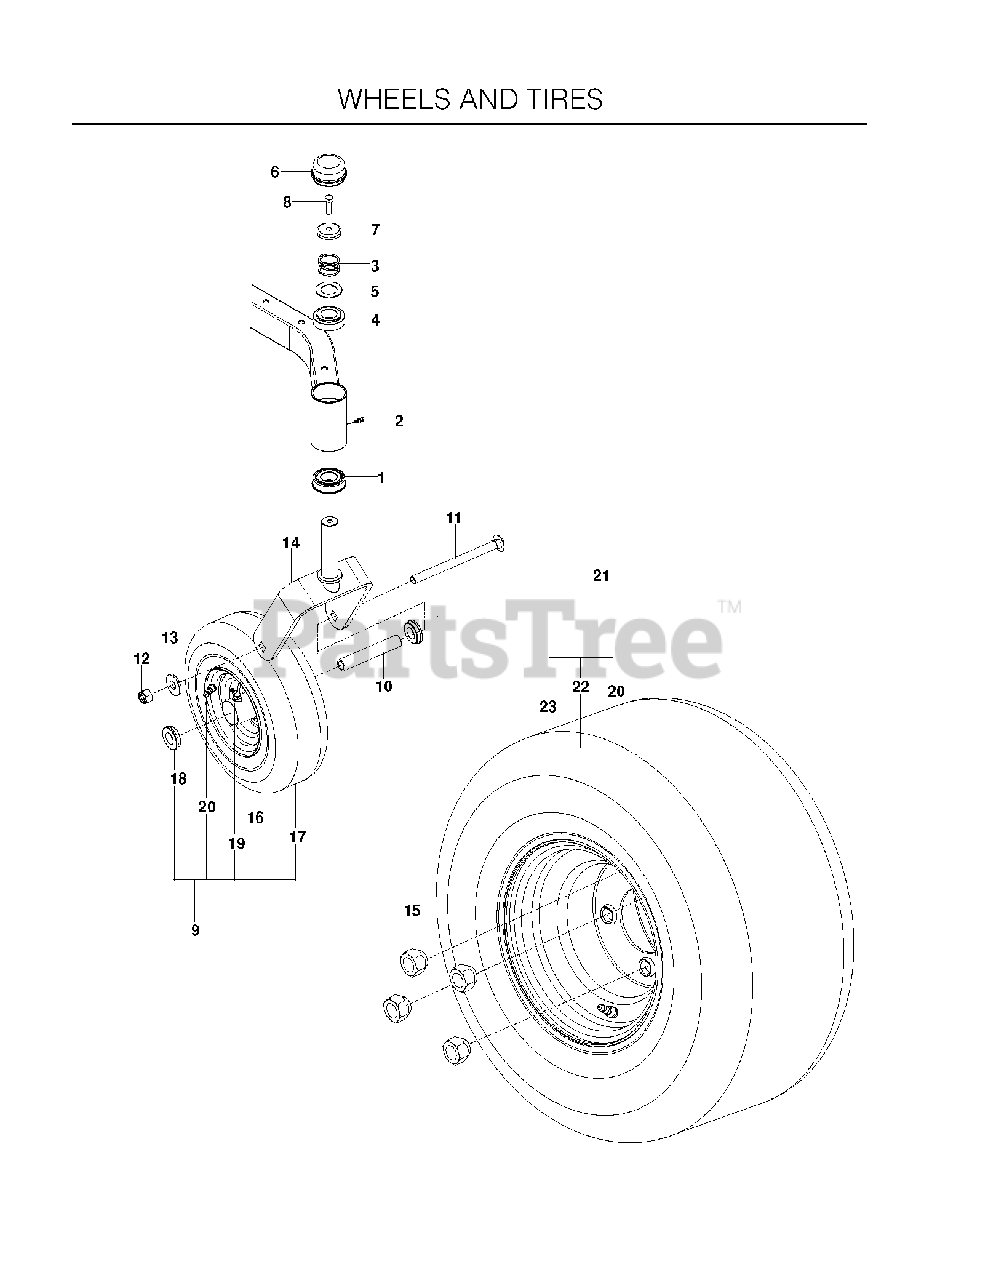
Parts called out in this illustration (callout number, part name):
1	BEARING FLANGED
2	ZERK, 3/16, DRIVE IN
3	SPRING, CASTER
4	BUSHING, CASTER
5	WASHER, 1.025 ID X 1.64
6	GREASE CAP
7	CASTER.PLUG
8	5/16-18X1 HHB G5W/NY
9	WHEEL ASSY, WIDE, RZ
10	SPACER, PIVOT
11	RHSNB 1/2-13 X 7.5
12	NUT 1/2-13 HEX CNTRLK GR 5 ZD
13	WASH USS FLAT 1/2
14	YOKE.CASTER.ORANGE
15	LUG NUT 1/2F
17	TIRE.11"X4"-5.4PLY.SMOOTH.KEND
18	BUSHING, WHEEL, 3/4"
19	ZERK
20	VALVE STEM TR-412
21	TIRE ASM, 20 X 8-8
22	TIRE 20 X 8, TURF
23	RIM.8X7.W/8".OFFSET.SILVER.ZTR
